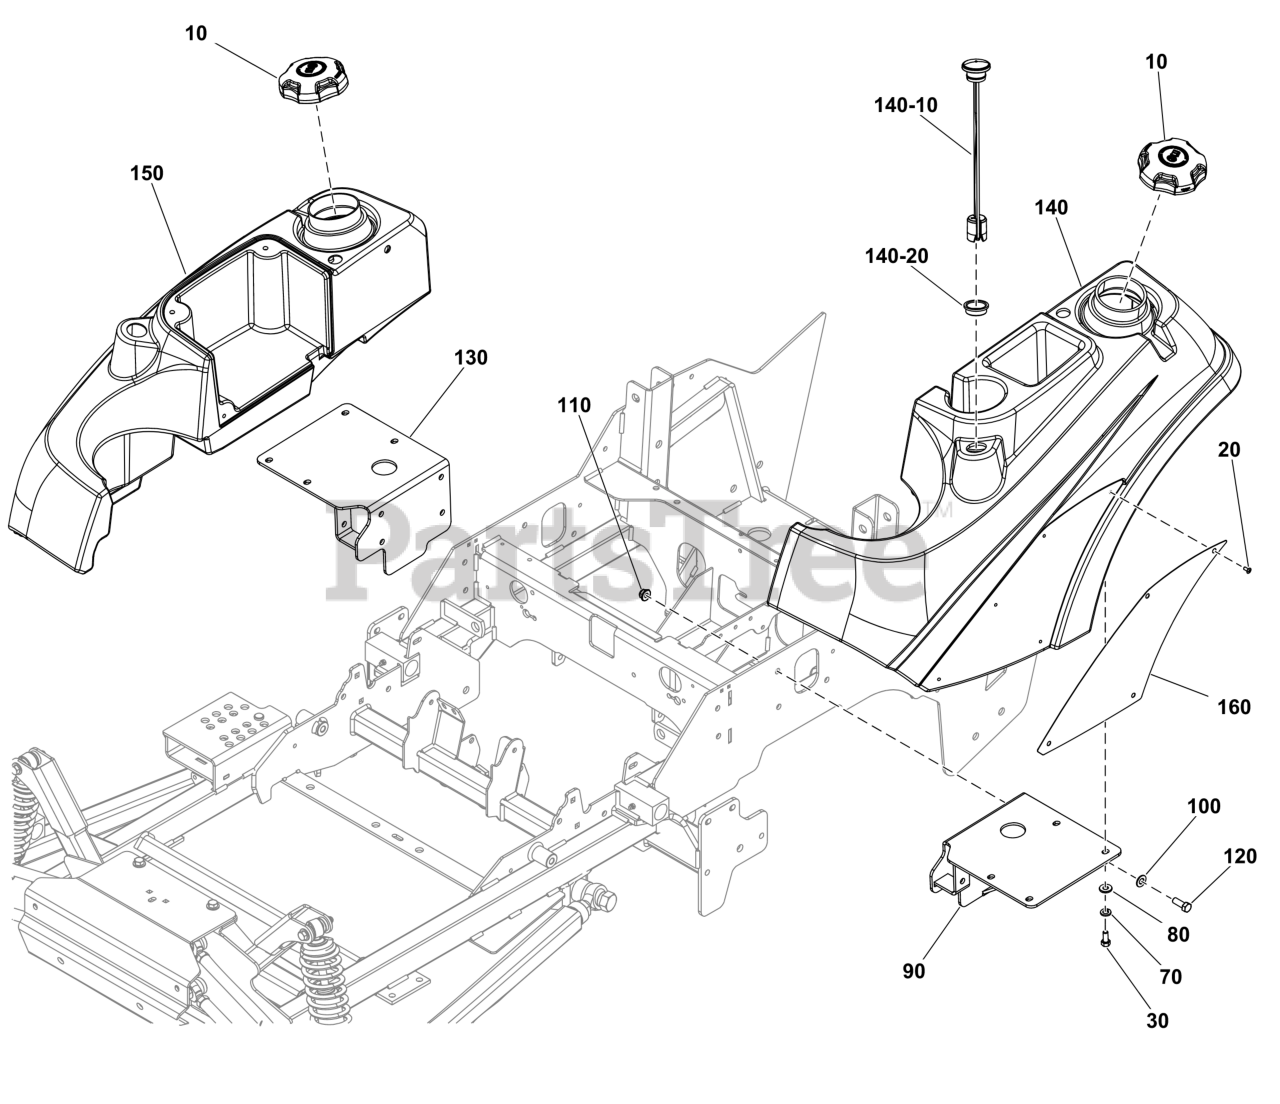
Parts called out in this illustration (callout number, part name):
10	CAP, FUEL TANK
20	SCREW, #10-24 X 3/8"
30	BOLT, 5/16-18 X 3/4"
70	WASHER, 5/16" LOCK
80	WASHER, 5/16" GD.9 FL
90	MOUNT, Tank
110	NUT, 3/8-16 HEX NYLOCK
120	BOLT, 3/8-16 X 1" GD5
130	MOUNT, Tank
140	TANK, FUEL
140-10	GAUGE, FUEL
140-20	GROMMET, FUEL GAUGE
150	TANK, FUEL
